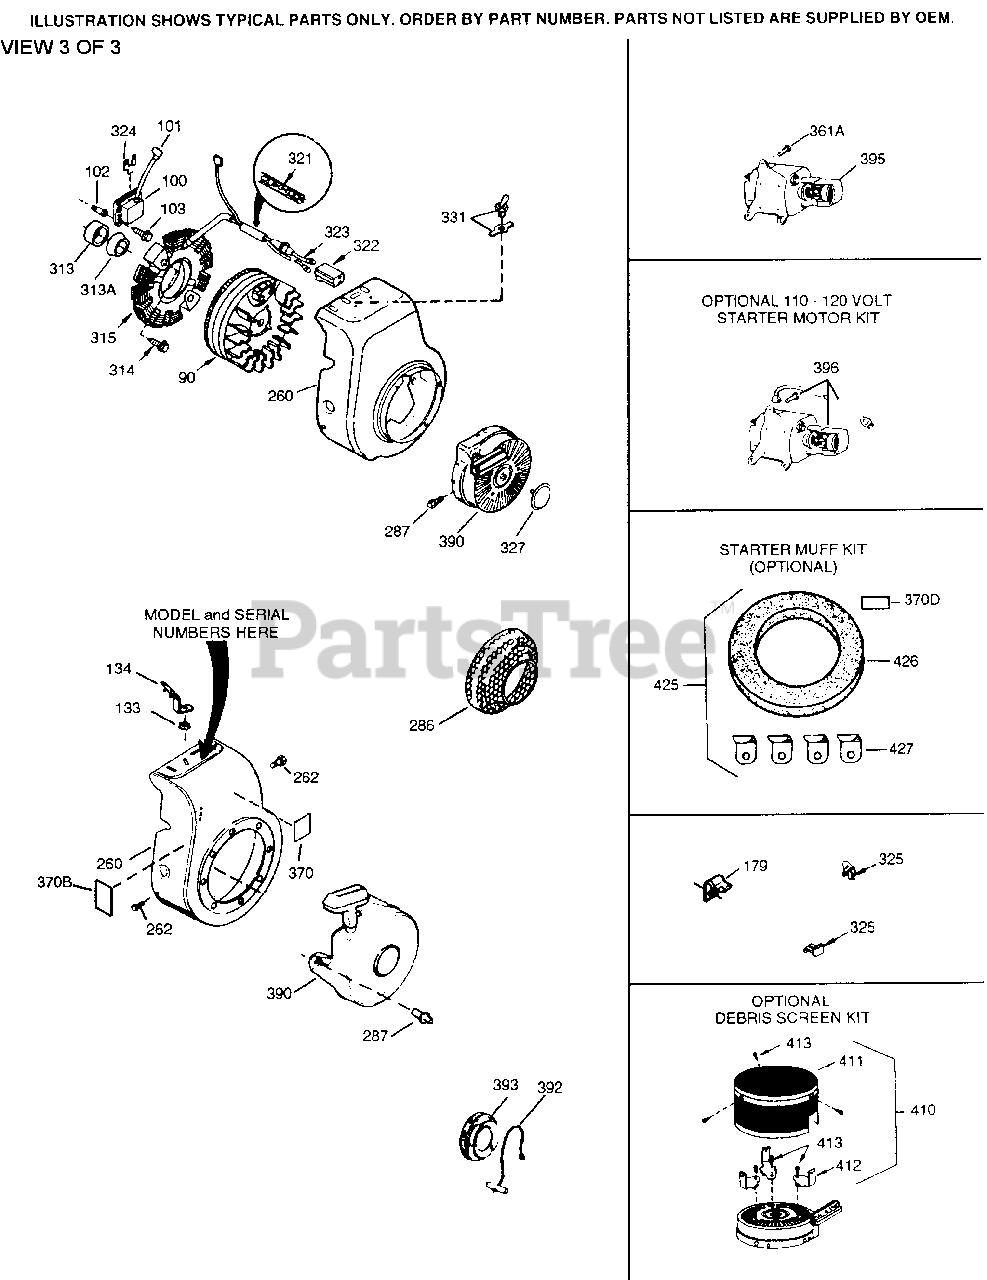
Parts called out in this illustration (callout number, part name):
90	Flywheel
100	Solid State Ignition
101	Spark Plug Cover
102	Solid State Mounting Stud
103	Screw, Torx T-15, 10-24 x 1
131	Screw, 5/16-18 x 1-1/2"
260	Blower Housing
261	Screw, 1/4-28 x 7/16"
370	Name Decal
370B	Throttle Decal
392	Starter Rope Ass'y.
393	Starter Pulley
